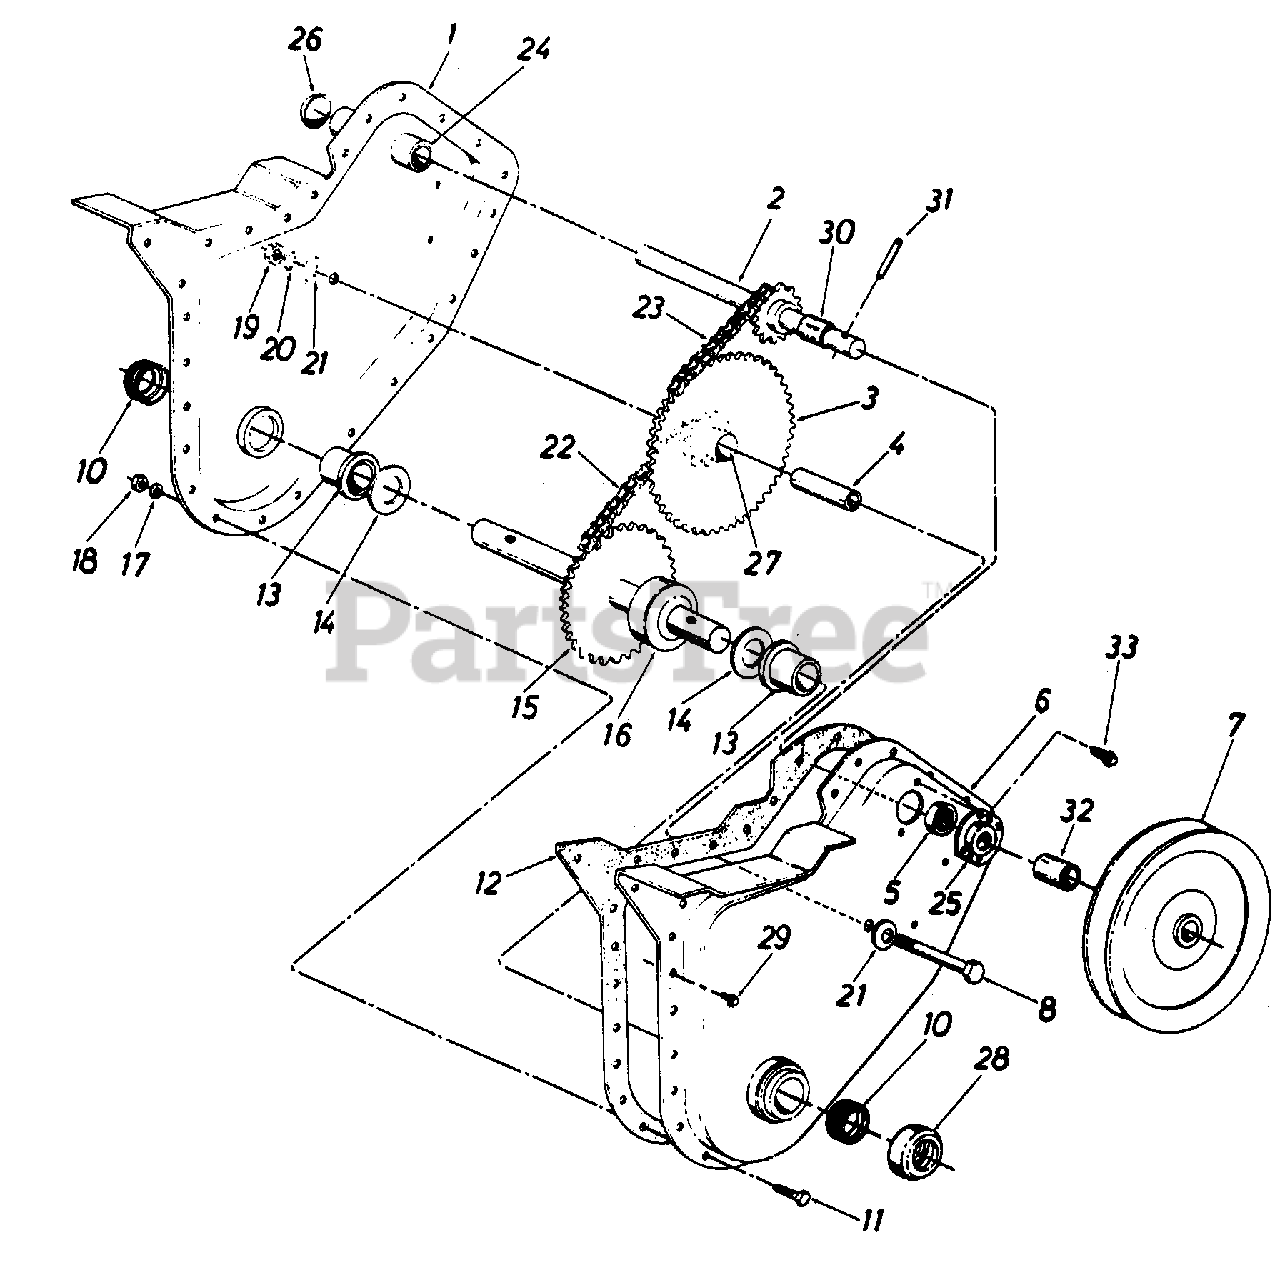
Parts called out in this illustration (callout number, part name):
1	Chain Case Ass'y. R.H.
2	Input Shaft Ass'y.
3	Hub and Sprocket Ass'y.
4	Bearing Inner Race
5	Ball Bearing
6	Chain Case Ass'y. L.H.
7	Pulley Chain Case 5 1/2 x 1/2
8	Hex Bolt 3/8-24 x 2.50" Lg.*
10	Seal
11	Hex Bolt 1/4-28 x .625" Lg.*
12	Gasket
13	Flange Brg. .879 I.D.
14	Fl-Wash. .88 I.D. x 1.50 O.D. x .030
15	Tine Shaft Ass'y.
16	Spacer 7/8" I.D. x 2.0" O.D. x.68" Lg.
17	L-Wash. 1/4" Scr.*
18	Hex Nut 1/4-28 Thd.*
19	Hex Ins. L-Nut 3/8-24 Thd.
20	L-Wash. 3/8" I.D.*
21	Bell-Wash. .406 I.D. x 1.130 O.D.
22	Chain #420 .50" Pitch x 38 Links
23	Chain #35 .375" Pitch x 50 Links
24	Bearing .62" I.D. x .813 O.D. x 1.31
25	Bearing Housing
26	Expansion Plug 13/16" Dia.
27	Bearing
28	Dust Capt
29	Hex Wash. Hd. Self-Tap Scr. 1/4-20 x .50" Lg.
30	Spacer .630 I.D. x .77 O.D. x .38" Lg.
31	Spring Pin Spiral 1/4" Dia. x 11/2" Lg
32	Spacer .647 x 1.25"
33	Hex Wash. Hd. Self-Tap Scr. 1/4-20 x .38" Lg.
